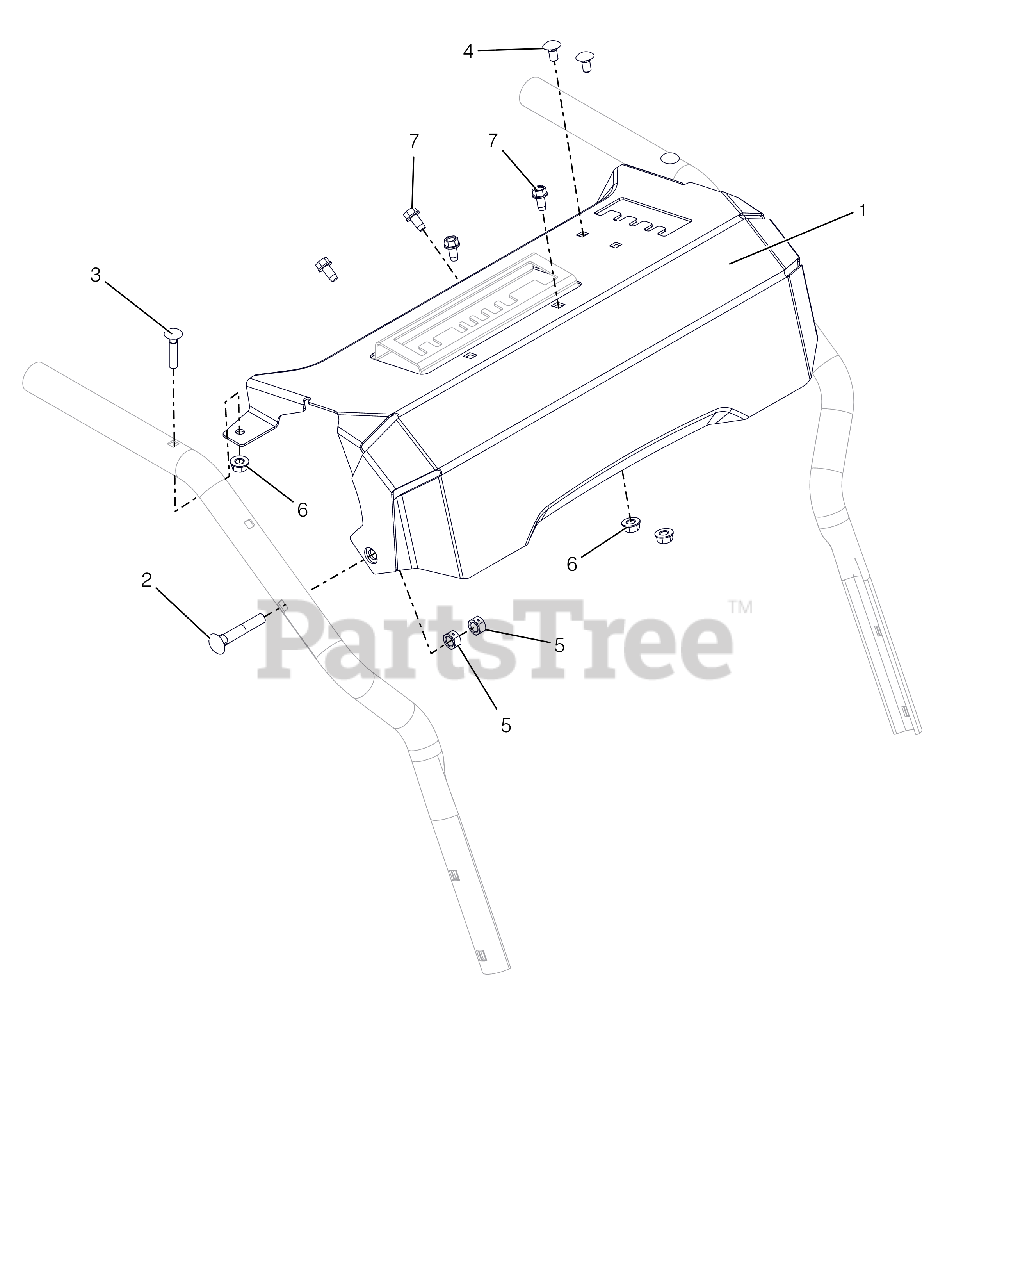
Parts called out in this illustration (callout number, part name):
1	CTRL PANEL W/DECAL-SNOTEK REMO
2	BLT-RDHDXLSQNK .31-18X2.0 G5YZ
3	BLT-RDHDXLSQNK.25-20X1.25 G5ZC
4	@BLT-RDHDSQNK .25-20X.50 G5YZ
5	@NUT-LK-CTR .31-18 YWZC
6	@NUT-LK-TOP-FLG .25-20 YWZC
7	SCR-TAP .25-20X.50 HWH TR YWZ
